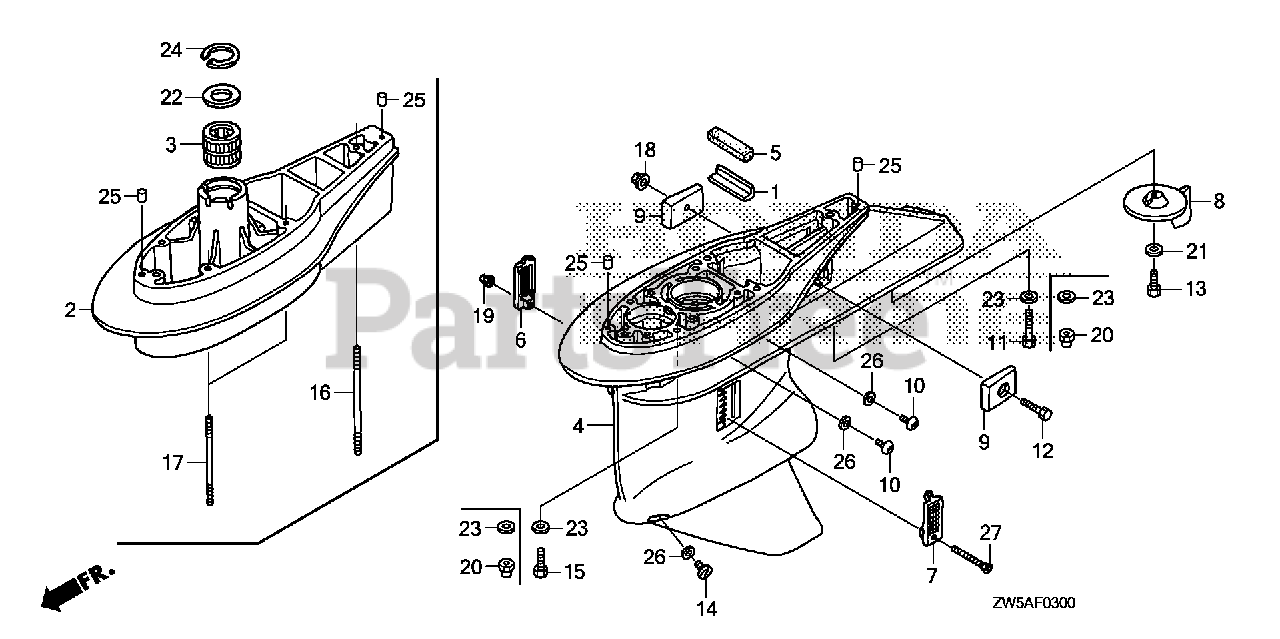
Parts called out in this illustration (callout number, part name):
1	PLATE, RUBBER SETTING
4	CASE, GEAR *NH282MU* (OYSTER SILVER METALLIC-U)
5	GROMMET, GEAR CASE
6	SCREEN, R. WATER
7	SCREEN, L. WATER
8	TAB, TRIM *NH282MU* (OYSTER SILVER METALLIC-U)
9	METAL, ANODE
10	BOLT, OIL CHECK
11	BOLT, HEX. (10X80)
12	BOLT, HEX. (6X32)
13	BOLT, HEX. (8X25)
14	BOLT, DRAIN PLUG
15	BOLT, HEX. (10X40)
18	NUT, SELF-LOCK (6MM)
19	NUT, SELF-LOCK (5MM)
21	WASHER, PLAIN (8MM)
23	WASHER, PLAIN (10MM)
25	PIN, DOWEL (6X10)
26	O-RING (6.9X1.45)
27	SCREW, OVAL (5X45)
